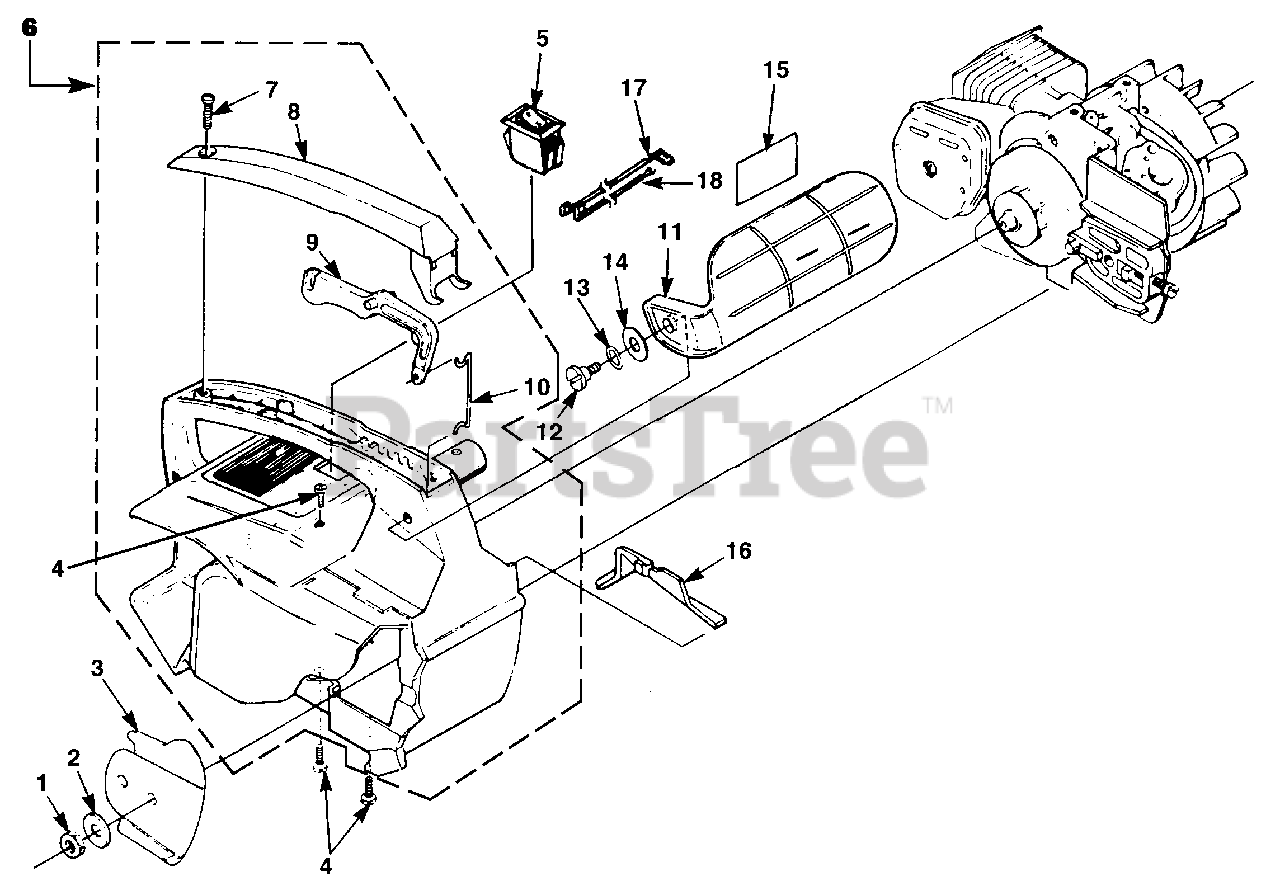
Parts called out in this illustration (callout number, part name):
1	NUT - Guide Bar
2	WASHER - Flat
3	PLATE - Guide Bar
4	SCREW - Pan Hd. (10-24 X 3/4")
5	SWITCH - Rocker
6	ENGINE HOUSING KIT
7	SCREW - Pan Hd. (#10 X 5/8")
8	COVER - Handle
9	TRIGGER
10	ROD - Throttle
11	HANDGUARD
12	SCREW - Shoulder (#10 X .560)
13	WASHER - Curved Spring
14	WASHER - Flat
15	DECAL - Handguard
16	COVER - Air Filter
17	LEAD - Ring Term.
18	LEAD - Double Flag
